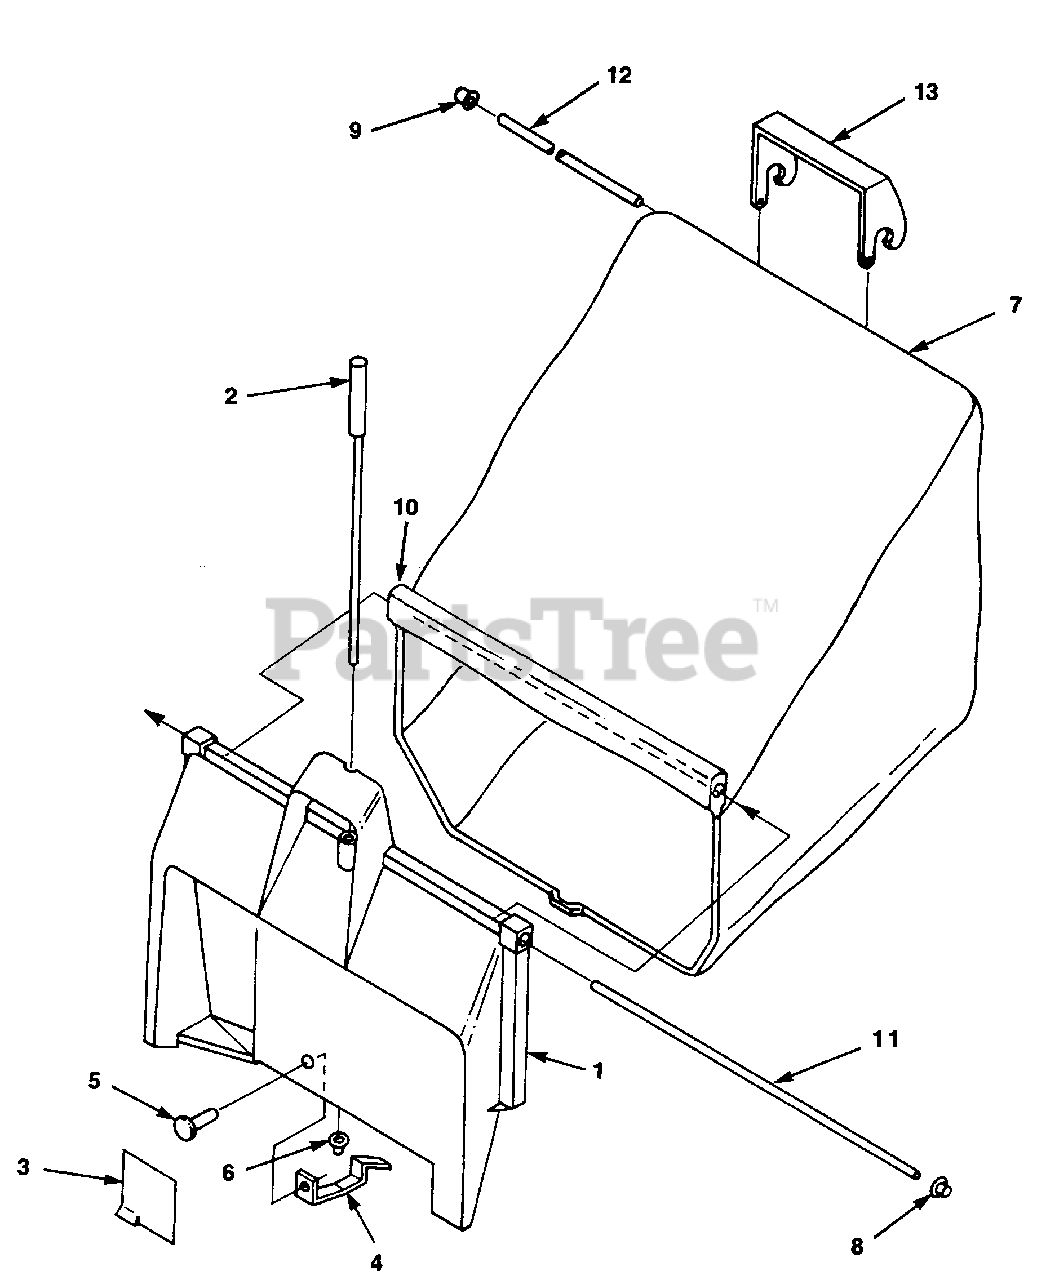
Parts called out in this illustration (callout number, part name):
1	ADAPTER ASSY.
2	ROD - Latch release
3	DEFLECTOR
4	Latch - bag release
5	RIVET 5/32 x 3/8"
6	NUT - Pal
7	BAG - Replacement
8	NUT - Pal
9	RETAINER - Bag rod
10	ROD - Bag support
11	ROD - Bag hinge
12	ROD - Bag
13	HANDLE-Bag
